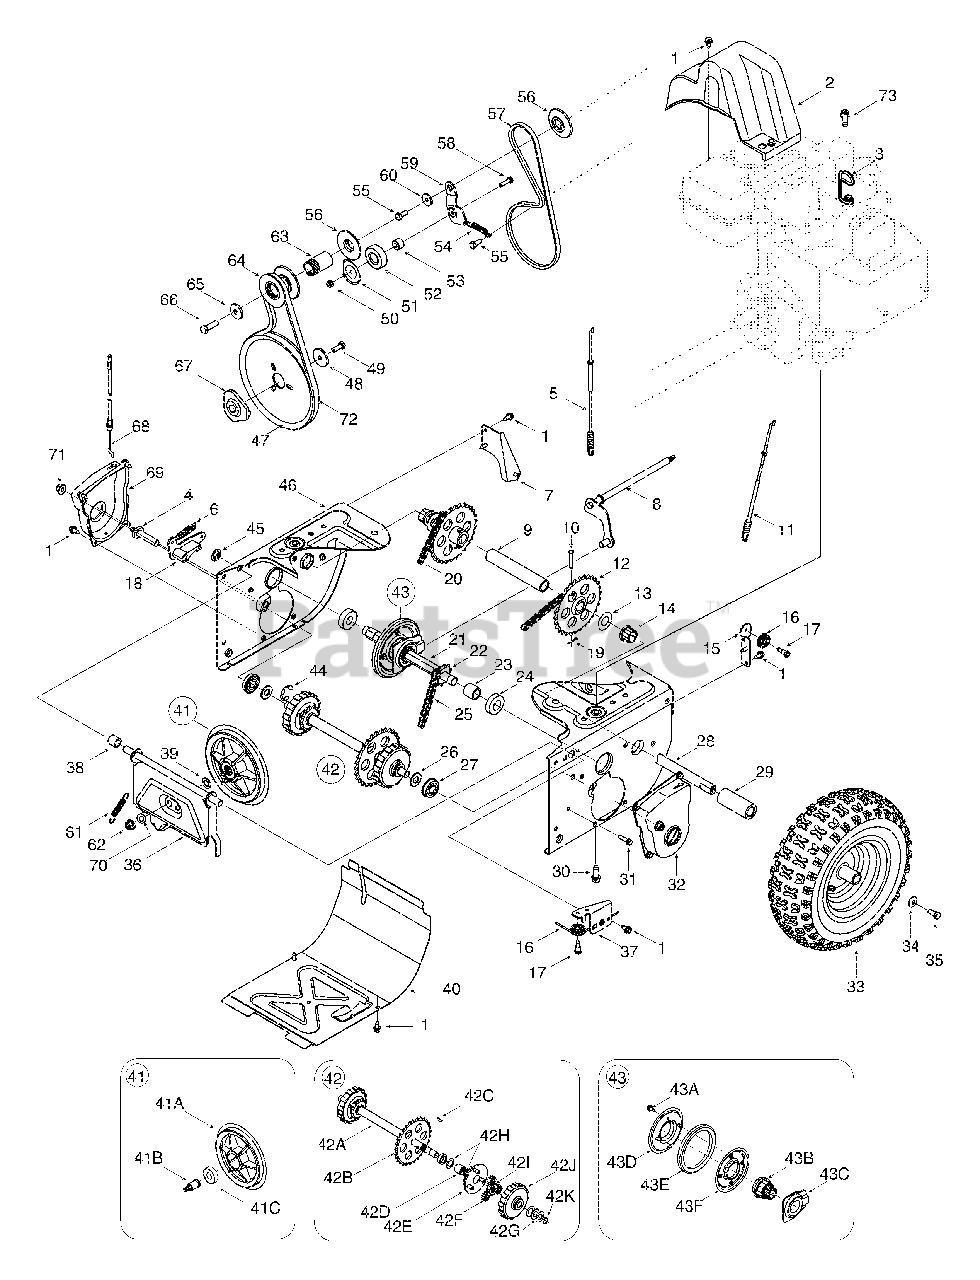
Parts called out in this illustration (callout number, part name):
1	AB Screw, 1/4-20 x 0.625
2	Belt Cover
3	Cable Guide
4	Actuator Shaft
5	Drive Clutch Cable
6	Extension Spring
9	Axle Support Tube
10	Clevis Pin
11	Auger Clutch Cable
12	Sprocket
13	Flat Washer
14	Hex Flange Bearing
17	C Screw, 1/4-28 x 0.375
18	Dogg Assembly - RH
19	Hairpin Clip
20	Chain
21	Drive Shaft
22	Sprocket
23	Spacer
24	Ball Bearing
26	Flat Washer
27	Ball Bearing
28	Axle
29	Spacer
30	TT Sems Screw, 3/8-16 x 1.0
31	TT Screw, 1/4-20 x 1.0
34	Bell Washer
35	Hex Bolt, 5/16-24 x 0.75
38	Spacer
39	Flat Washer
41A	Friction Wheel Disc
41B	Friction Disc Bearing Pin
41C	Ball Bearing
42	Drive Shaft Assembly
42A	Drive Shaft
42B	Sprocket
42D	Spacer
42E	Planetary Carr. Assembly
42F	Gear, 12T
42G	Flat Washer
42H	Flat Washer
42I	Gear,18T
42J	Planetary Ring Gear
42K	Retainer Ring
43	Friction Wheel Assembly
43A	AB Screw, 1/4-20 x 0.625
43B	Friction Wheel Hub
43C	Bearing Assembly
43D	Friction Plate
43E	Friction Wheel Rubber
43F	Friction Plate
44	Retainer Ring
45	Speed Nut
48	Flat Washer
49	Hex Bolt, 5/16-24 x 0.875
50	Flange Lock Nut, 1/4-20
51	Bearing Washer
52	Ball Bearing
53	Spacer
54	Extension Spring
55	Hex Bolt, 5/16-24 x 0.75
56	Pulley Half
57	V-Belt, 3/8 x 28.6
58	Hex Bolt, 1/4-20 x 1.0
61	Extension Spring
62	Jam Nut, 3/8-24
63	Spacer
64	Pulley Half
65	Flat Washer
66	Hex Bolt, 3/8-24 x 1.25
67	Pulley Adapter
68	Steering Cable
69	Shaft Retainer - RH
70	Bell Washer
71	Flange Lock Nut, 3/8-16
72	V-Belt,.500 x 35.00 Lg
73	TT Screw, 5/16-18 x 1.00
